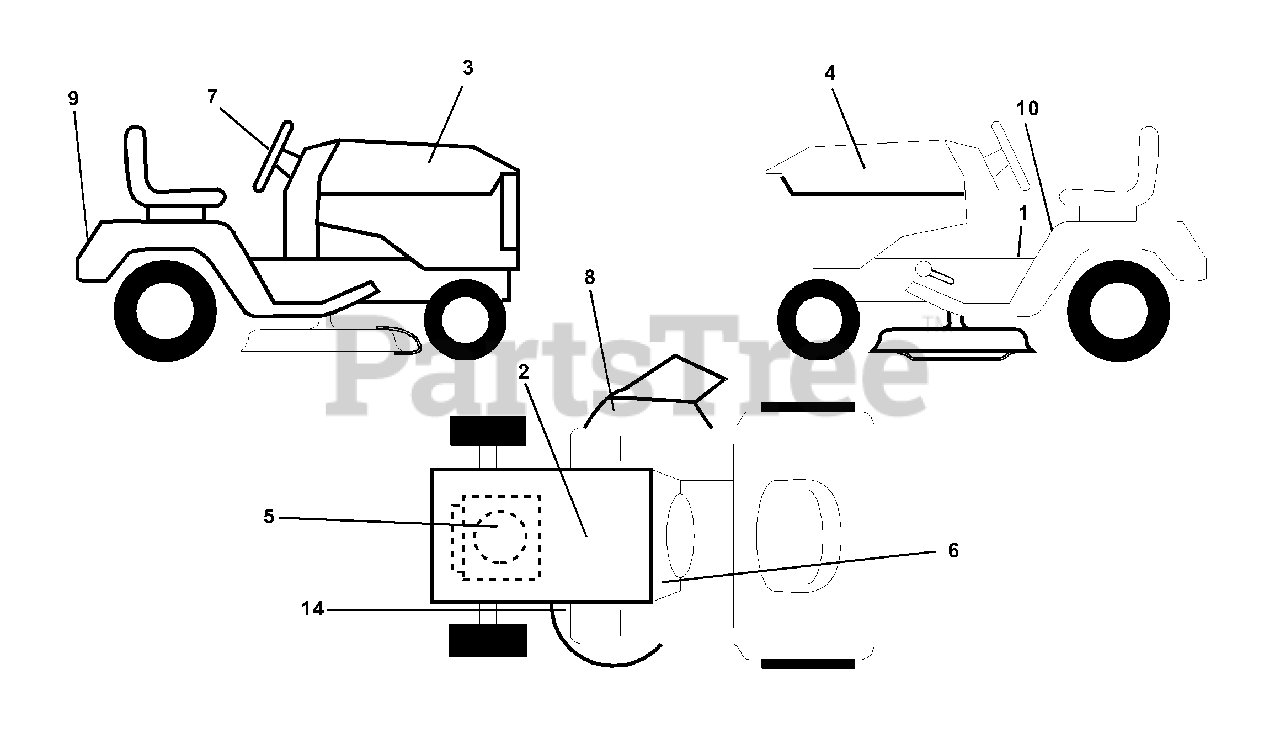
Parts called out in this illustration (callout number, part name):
1	Decal Oper. Step Thru E/F
2	Decal Battery
3	Decal Hood RH
4	Decal Hood LH
5	Decal HP Engine
6	Decal Dash Logo
7	Decal Wheel Steering
8	Decal Warning Multi-Languages
9	Decal Fender Husq
10	Decal Fender Danger E/F
14	Decal V-Belt Schematic
